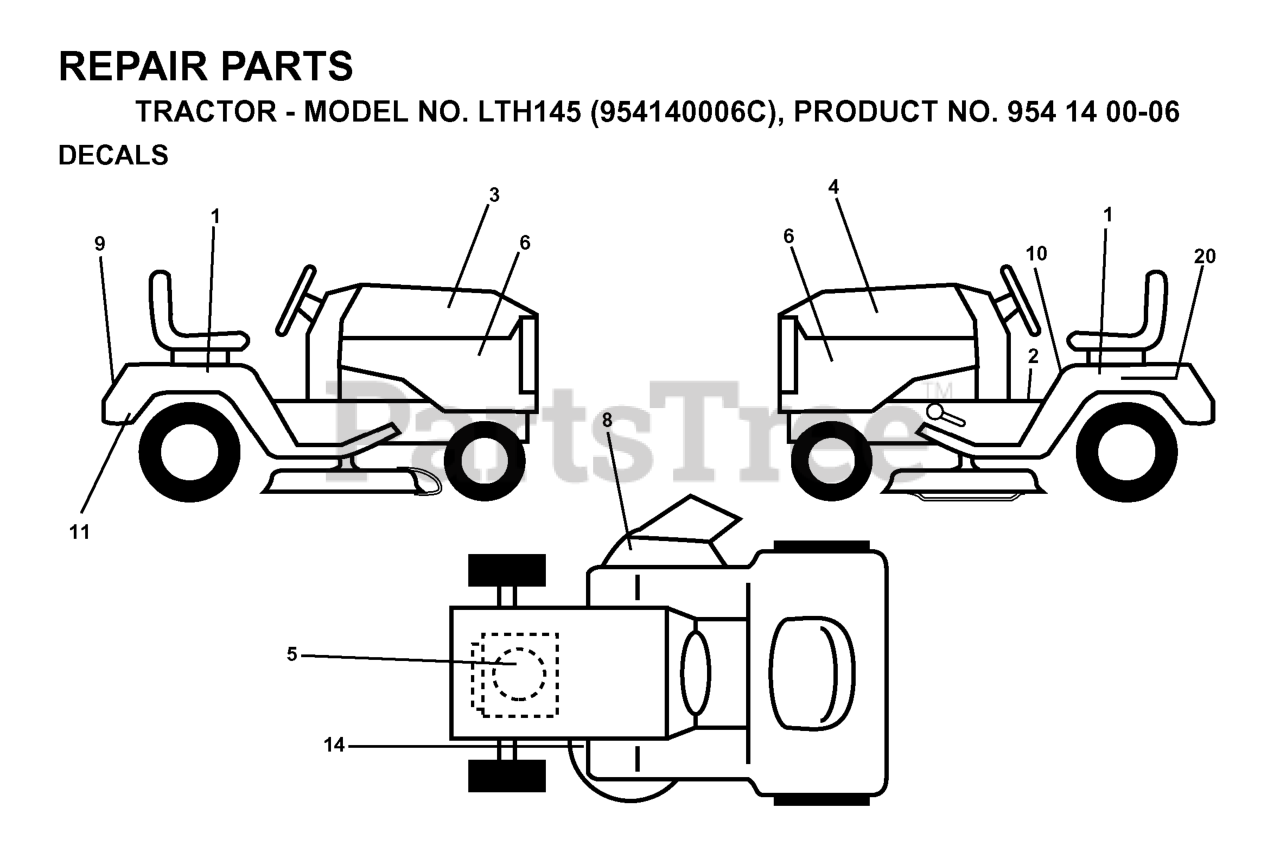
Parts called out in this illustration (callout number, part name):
6	DECAL PNL SIDE
8	DECAL WARNING (ENGLISH/FRENCH)
9	DECAL FENDER HUSQ
10	DECAL FENDER DANGER
11	DECAL DRAWBAR CONTROL
14	DECAL V BELT SCHEMATIC
20	DECAL BTRY SYMBOLS
